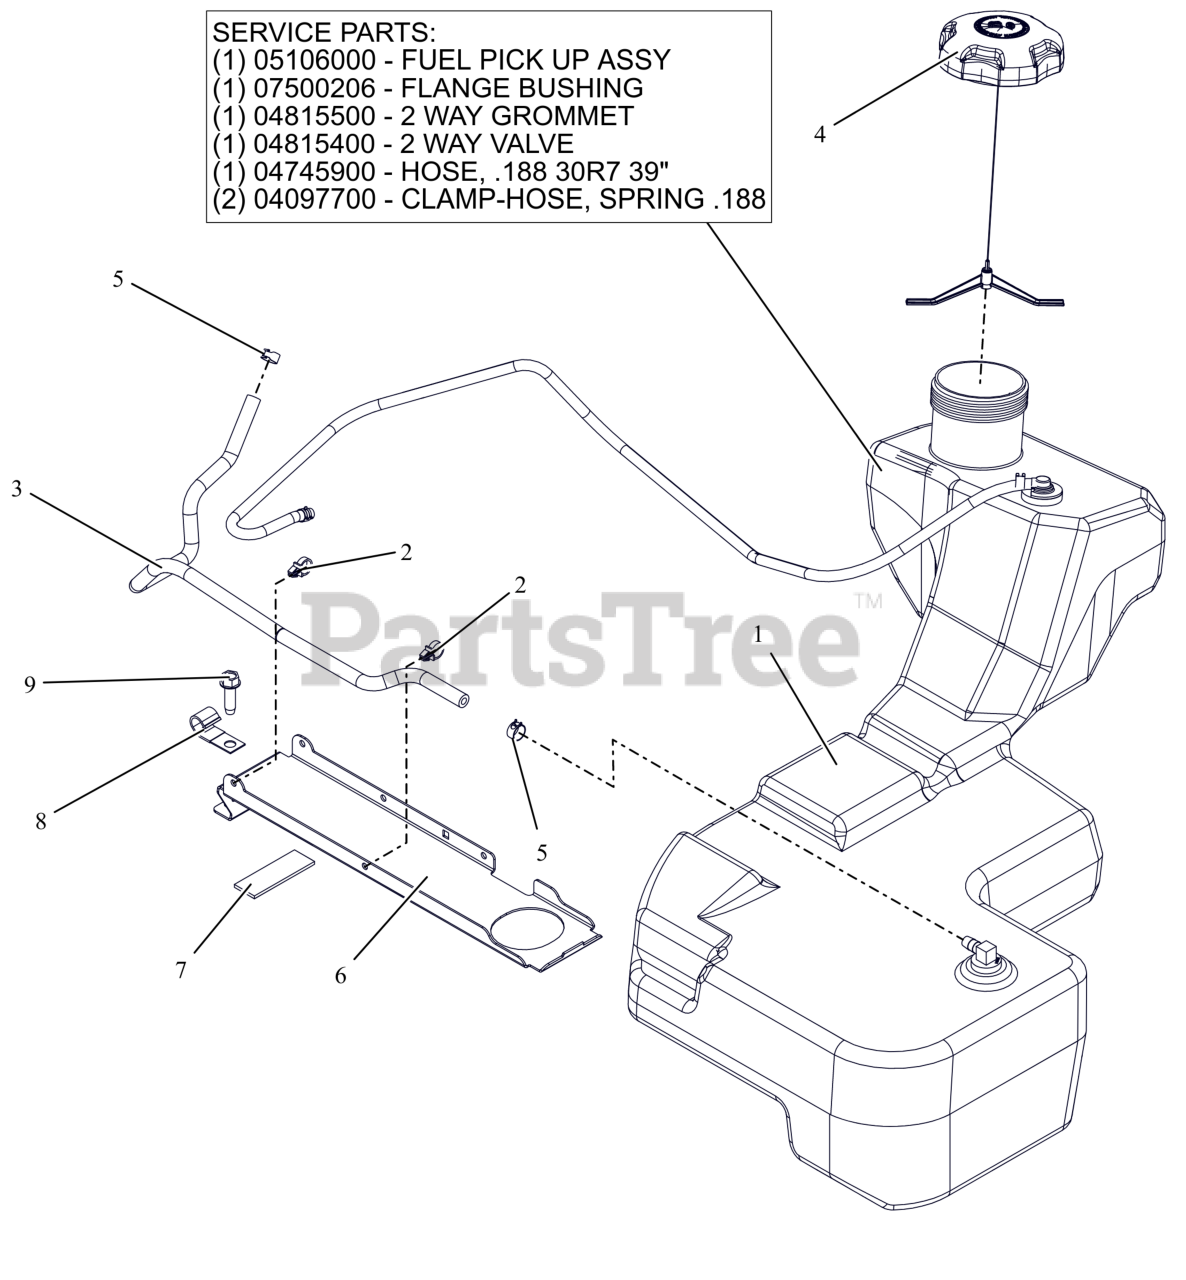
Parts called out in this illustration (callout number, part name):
1	ASM, FUEL TANK-HD
1	ASM, HD FUEL PICK-UP
1	BSHG-FLG .375X1.062X.625 NITR
1	GROMMET, 2-WAY
1	VALVE, 2-WAY
1	HOSE, .188 30R7 BULK
1	CLAMP-HOSE, SPRING .188
2	ROUTING CLIP (1/2" ID)
3	1 INCH OF HOSE, .25 LOW-PERM BULK GAS
4	CAP, FUEL - 3.50 RATCHET INLET VENT
5	CLAMP, FUEL LINE
6	BRKT, FUEL TANK HOLD DOWN
7	PAD,RBR 1.0"X3.0" W/ADHESIVE
9	SCR,TAP .375-16X1.25HWH TR ZCC
